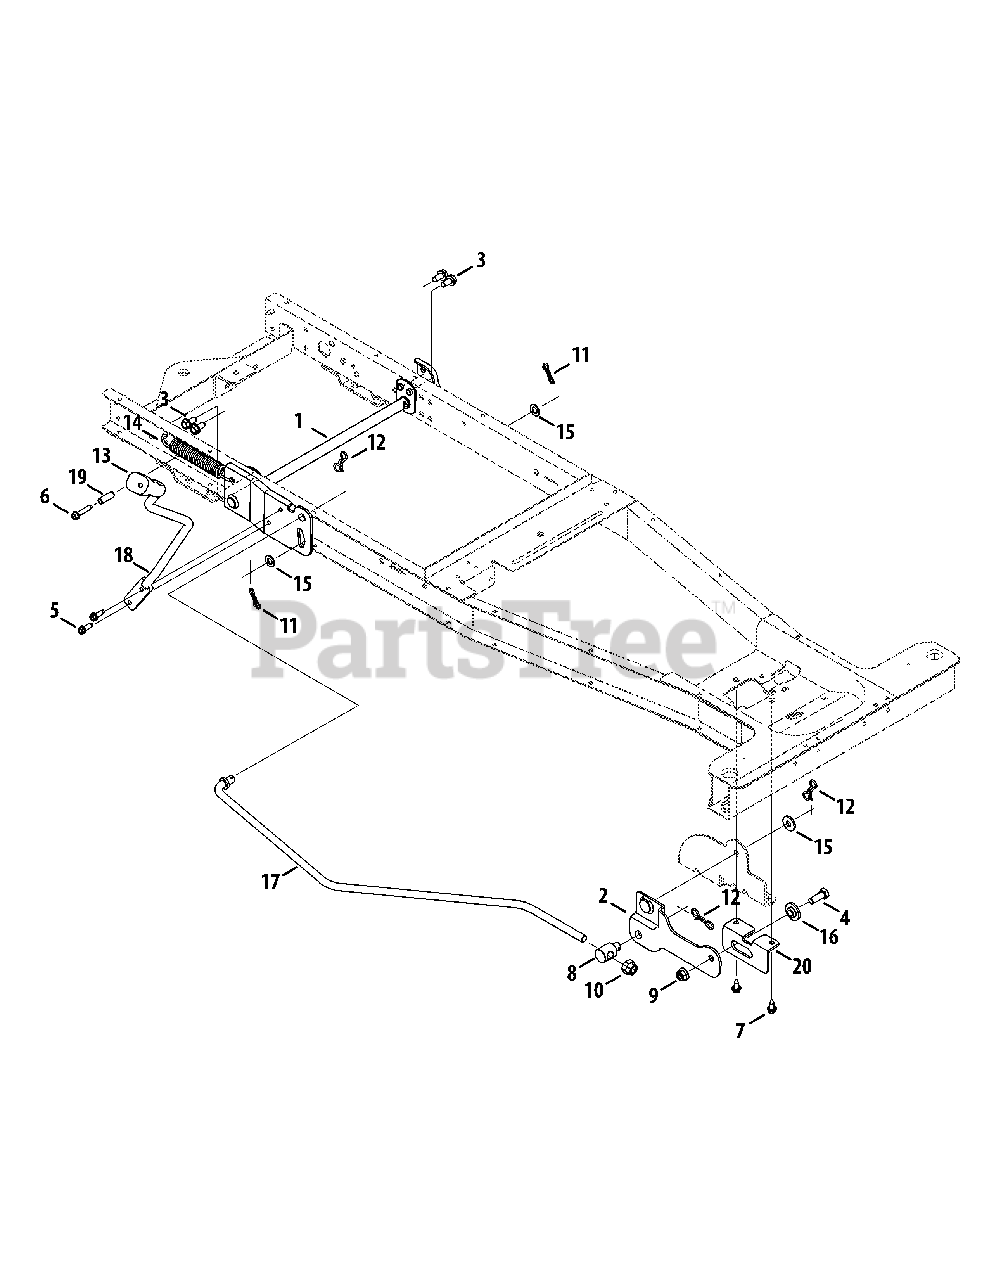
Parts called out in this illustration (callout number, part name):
1	Lift Assembly Shaft
2	Front Hanger Bracket Assembly
3	Tap Screw, 5/16-18x.750
4	Hex Head Screw, 3/8-16x1.00
5	Tap Screw, 1/4-20x0.750
6	Tap Screw, 1/4-20x1.250
7	Tap Screw, 1/4-20 X .625
8	Ferrule, .50 X .50
9	Flange Lock Nut, 3/8-16
10	Flex Lock Nut, 1/2-13
11	Bow-Tie Cotter Pin, 72
12	Bow-Tie Cotter Pin, 91
13	Grip Handle, 1/2
14	Extension Spring, .85 OD X 5.915 LG
15	Flat Washer, .406 X .875 X .059
16	Shoulder Spacer, .625 ID X .169
17	Lift Link Rod
18	Deck Lift Rod
19	Spacer, .260 x .375 x 1.030 LG
20	Front Deck Mounting Bracket
